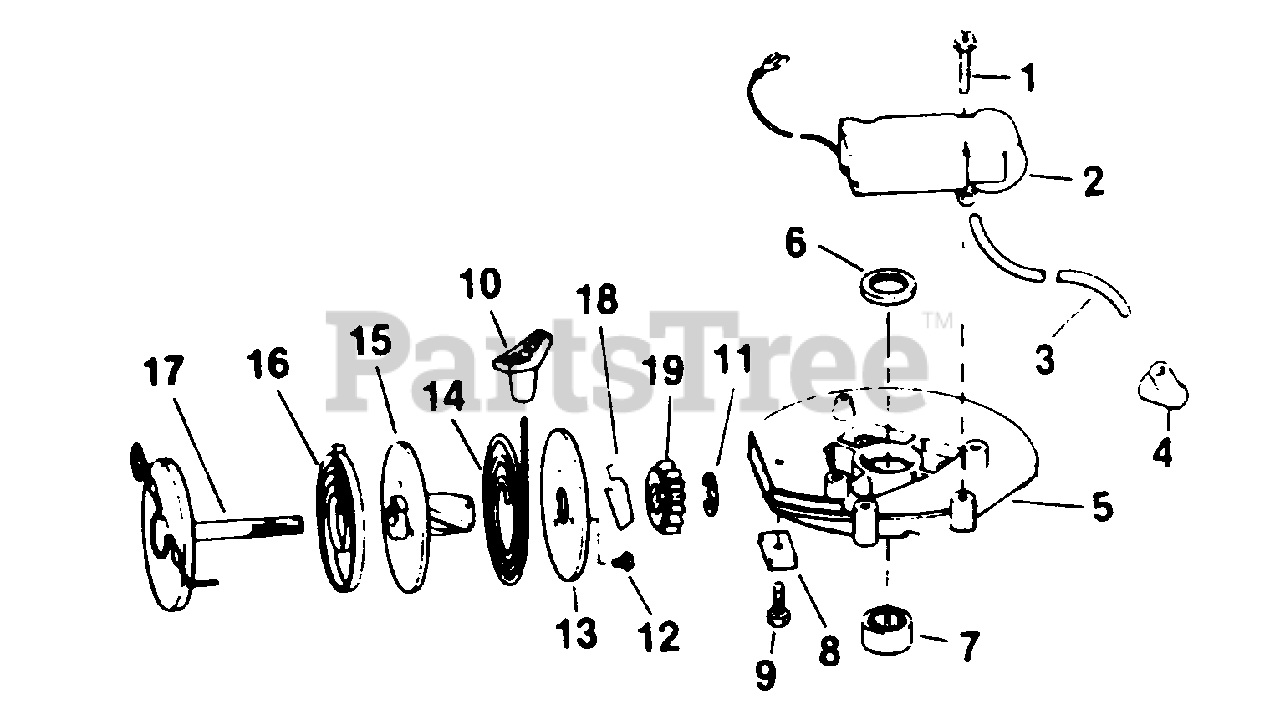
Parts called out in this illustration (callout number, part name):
1	Screw
2	C.D. Ignition Pack
3	High Tension Lead
4	Cover and Terminal Assembly
5	Arm. Plate, Bearing & Seal
6	Seal
7	Bearing
10	Handle
11	Retainer
13	Plate
17	Cup & Pin Assembly
